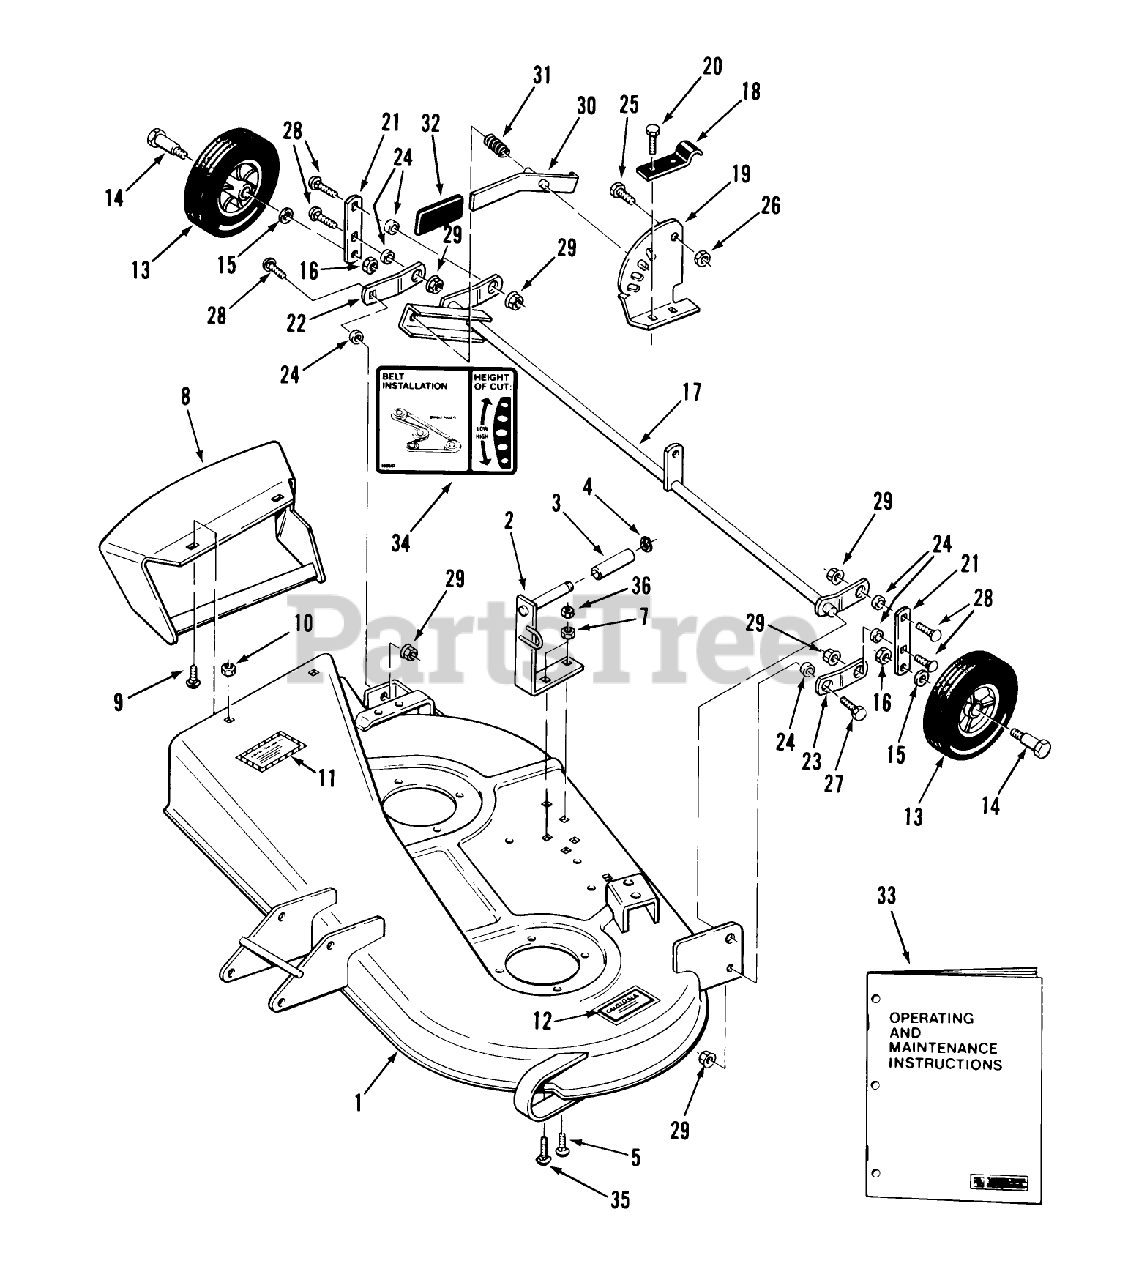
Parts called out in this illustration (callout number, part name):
1	ASSY 32" MOWER SI *R
20	Bolt
24	SPACER
31	SPRING-COMPRESSION
33	Operating Maintenance Instructions
